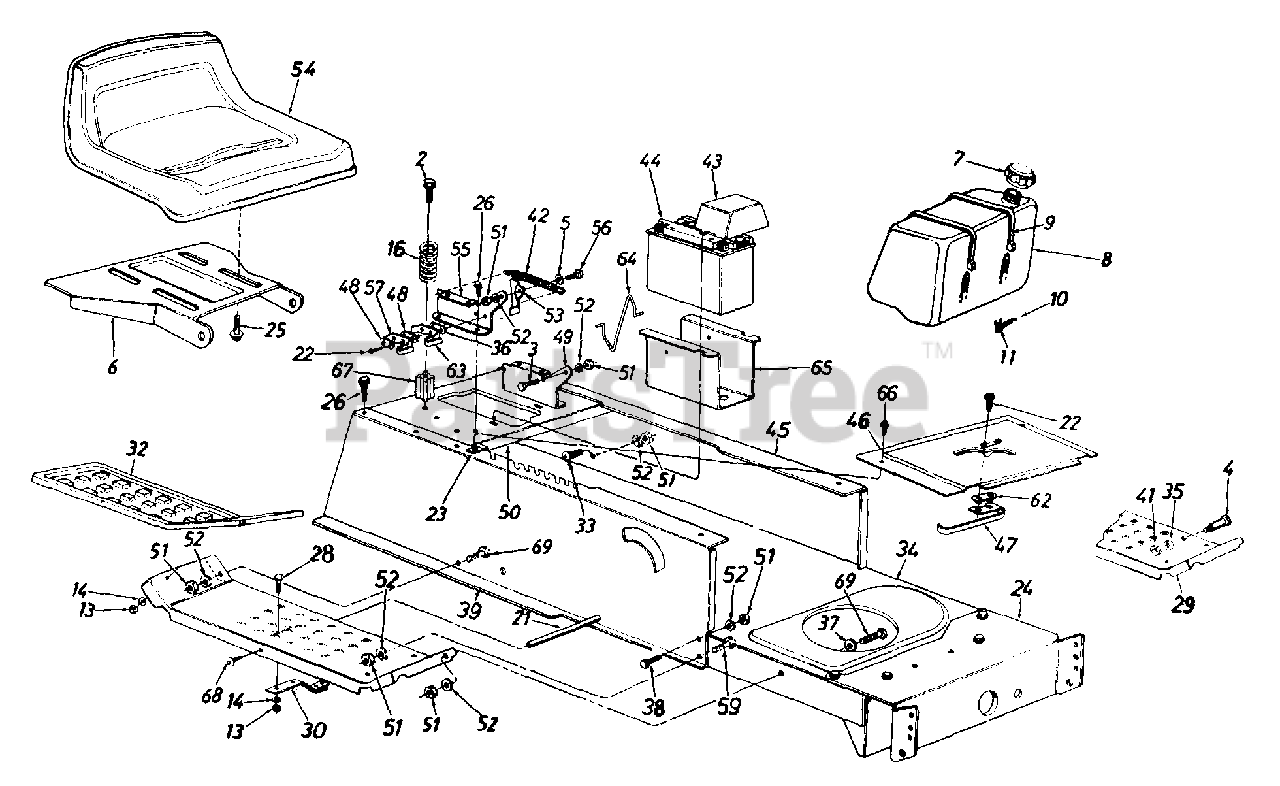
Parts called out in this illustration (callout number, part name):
2	Hex Wash. Hd. Tap Scr. 5/16-18 x 3.25" Lg.
3	Shld. Bolt .437" Dia. x .162"
4	Shld. Bolt .50" Dia. x .84"
5	Spr-Wash..445" I.D. x .75
7	Fuel Cap
9	Tie Strap
10	Fuel Line
13	Hex Nut 1/4-20 Thd.
14	L-Wash. 1/4" I.D.
16	Compression Spring
21	Running Board Rod
22	Hex Wash. Hd. AB-Tap Scr. #8 x .50" Lg.
23	Speed Nut #10Z
25	Hex Tap Scr. 3/8-16 x .75"
26	Hex Wash. Hd. AB-Tap Scr. 5/16 x .75" Lg.
28	Carriage Bolt 1/4-20 x .62"
32	Rubber Foot Pad - L.H.
33	Truss Mach. Scr. 5/16-18 x .75" Lg.
36	Insulator Boss Plate
37	Fl-Wash..344" I.D. x .625" O.D.
38	Hex Bolt 5/16-18 x .75" Lg.
42	Extension Spring 5.31" Lg.
43	Battery Cover
44	12-V Battery
47	Reverse Safety Switch
48	Insulator Plate
52	L-Wash. 5/16" I.D.
53	Seat Lift Brkt.
54	Seat(134A676F190)
56	Shld. Bolt .437" Dia. x .268"
57	Spring Switch
59	Hex Wash. TT-Tap Scr. 5/16-18 x 7/8" Lg.
62	Insulator Nut Plate
63	Safety Switch (Seat)
64	Battery Tray Clip (Single Cylinder)
65	Battery Tray
66	Truss Mach. B-Tap Scr. #10 x .5" Lg.
67	Spring Spacer
68	Pan Hd. Cutting Scr. 5/16-18 x .75" Lg.
69	Hex Bolt 5/16-18 x .75" Lg.
